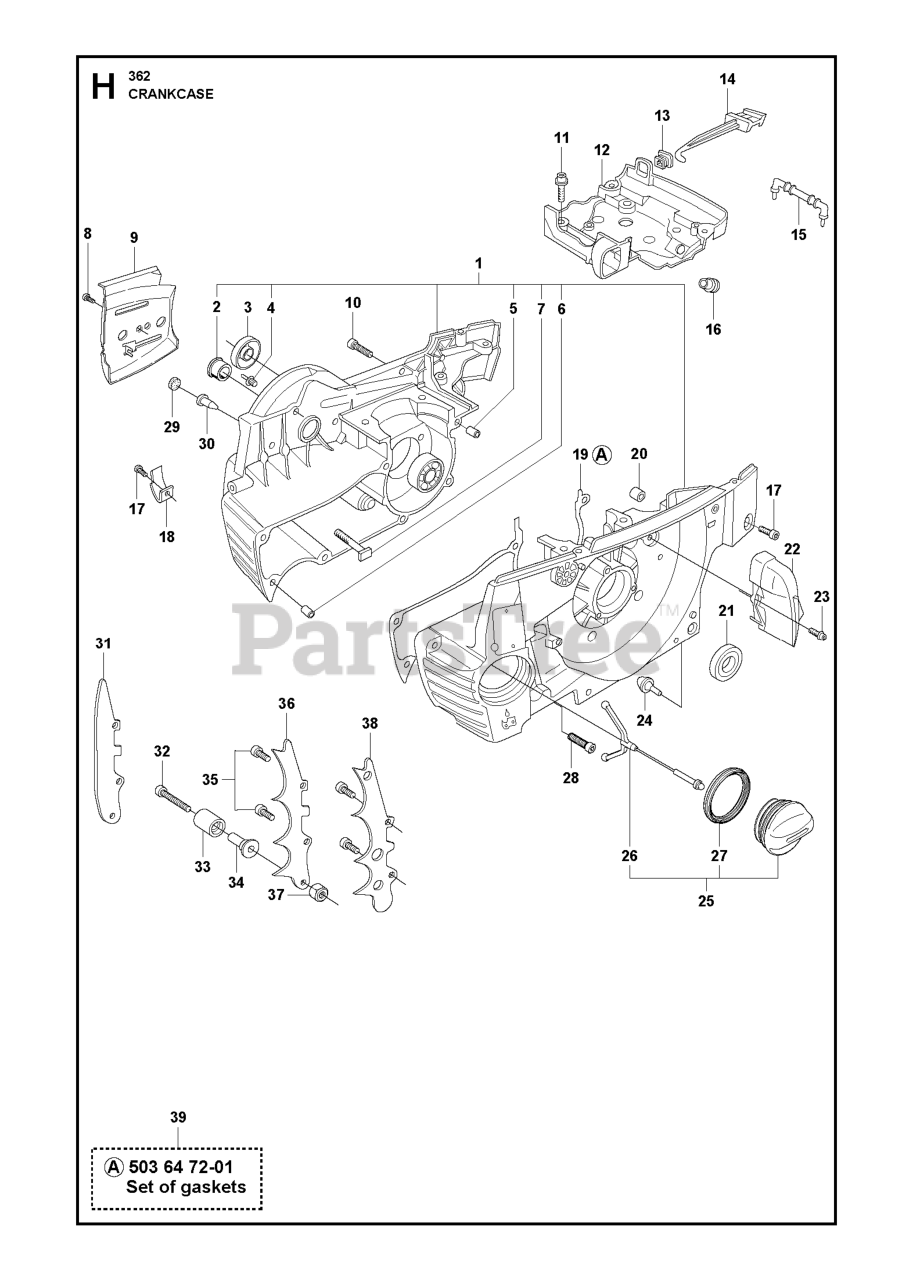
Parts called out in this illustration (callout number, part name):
1	CRANKCASE ASSY
1	DECAL.FENDER.WARNING.ENG
2	EMBLEM.HOOD.HUSQ.DEALER
3	DECAL.SDPNL.2348LS.ENDUR.HUSQ
4	DECAL.ENG.BSM44.23.ENDUR.27817
5	DECAL HOOD CUST. RESP.
6	DECAL.ENG.B&S.13.5HP..IC/OHV
8	DECAL.WARN.KEEP.HAND.AWAY
9	DECAL BTRY SYMBOLS
11	SCREW
12	DECAL.MOWER.SCH.48/54
17	SCREW IHSCM
18	CHAIN CATCHER
23	SCREW
25	TANK CAP
29	PLUG
30	VALVE-CHECK (DUCKBILL)
32	SCREW IHSCFM
34	CHAIN CATCHER
36	FELLING DOG
38	FELLING DOG
39	GASKET SET
